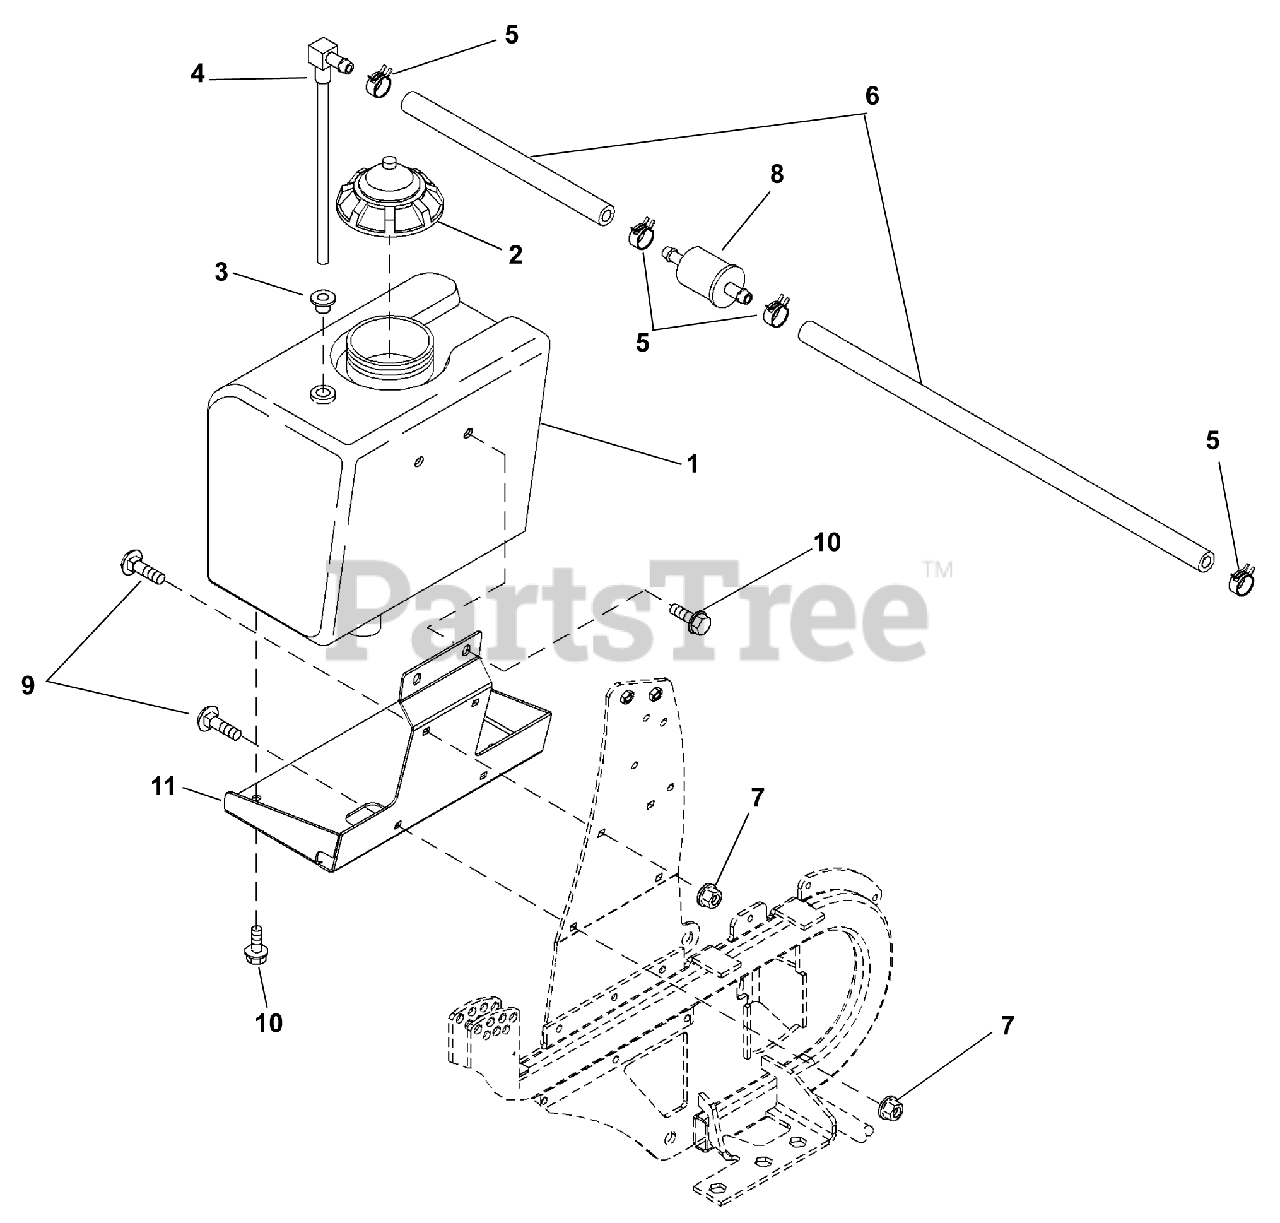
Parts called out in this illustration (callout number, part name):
1	TANK-FUEL 48P/S W/CAP W/O LOGO
2	CAP, FUEL
3	GROMMET
4	FUEL PICKUP
5	CLAMP
6	HOSE, 10 FT SERVICE #
7	NUT-LK-NYL M10-1.5 YWZC
8	FILTER
9	CARRIAGE BOLT, M10 X 1.5 X 25
10	BLT-HEX M8 X 1.25X16 YWZC
11	BRACKET, FUEL TANK MOUNTING
